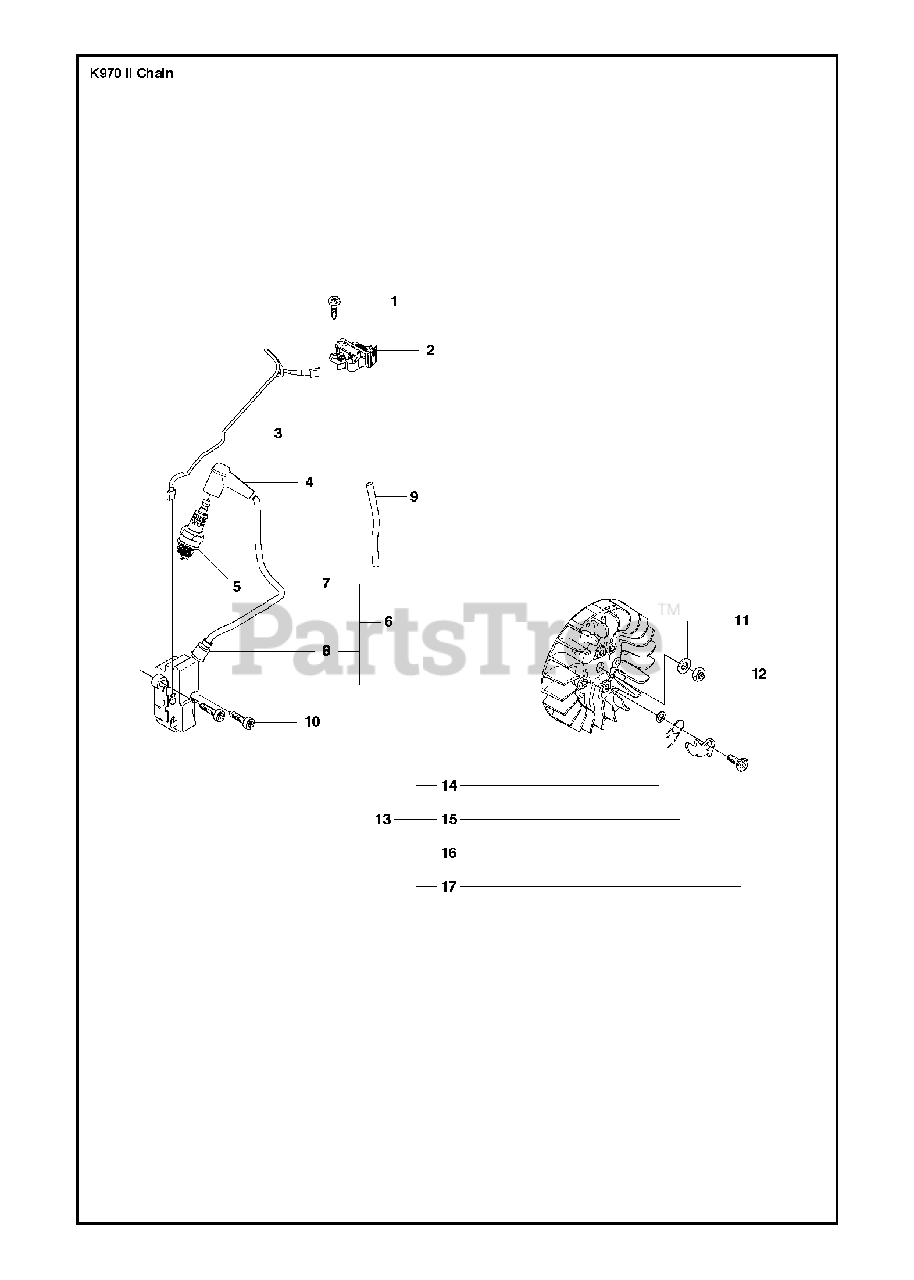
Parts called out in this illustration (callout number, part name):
1	SCREW CCRPANT
2	STOP SWITCH
4	SPARK PLUG CAP
6	IGNITION MODULEIncl. 7 - 8
7	IGNITION CABLE
10	SCREW ITXSCM
13	FLYWHEELIncl. 14 - 17
17	SCREW
